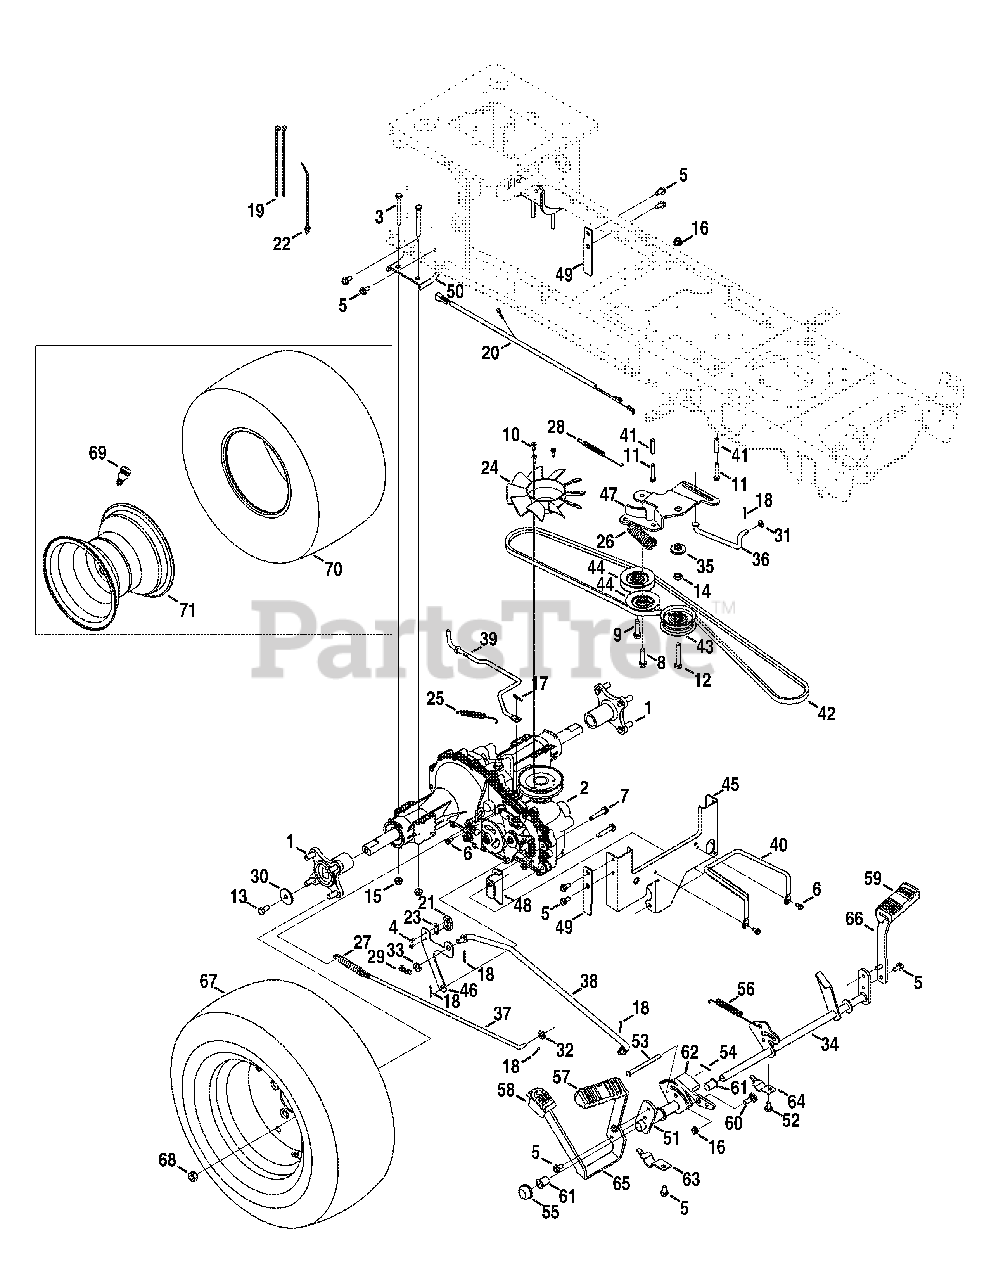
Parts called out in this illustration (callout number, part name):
1	Hub Assembly,Wheel
2	Transmission
3	Hex Screw, 5/16-18:3.00
4	Screw, #8-18:0.500
5	Taptite Screw, 5/16-18:.750
6	Taptite Screw, 1/4-20:0.500
7	Taptite Screw, 5/16-18:1.750
8	Taptite Sems Screw, 3/8-16:1.500
9	Taptite Sems Screw, 3/8-16:1.875
10	Screw, #12-24:0.625
11	Taptite Screw, 1/4-20:1.625
12	Hex Screw, 3/8-16:2.25
13	Hex Screw, 3/8-16:.750
14	Jam Nut, 7/16-20
15	Flangelock Nut, 5/16-18
16	Flangelock Nut, 3/8-16
17	Cotter Pin, .072 DIA. x 1.13 LG
18	Cotter Pin, 3/32:1.0
19	Cable Tie, 3/16 x .05 x 7.4
20	Jumper Harness
21	Short Spring Switch
22	Push Mount Cable Tie 7.5 LG
23	Insulator Nut Plate
24	Blade Fan
25	Extension Spring, .50 DIA x 5.0 LG
26	Extension Spring, 1.00 DIA x 4.75
27	Extension Spring, .59 OD x 4.00 LG
28	Extension Spring, .38 DIA x 5.6
29	Extension Spring, .375 OD x 1.44 LG
30	Flat Washer, .390 x 1.500 x .134
31	Flat Washer, .330 x .630 x .0635
32	Flat Washer, .344 x .750 x .120
33	Flat Washer, .407 x .812 x .135
34	Brake Control Assembly
35	Shoulder Spacer, 1.375 x .380 x .183
36	Footpedal Bypass Transmission Rod
37	Brake Rod
38	Control Rod
39	Disengage Rod
40	Belt Keeper, 5/16
41	Spacer, 260 x .372 x 1.420 LG
42	V Belt, 4L x 77.0
43	Flat Idler Pulley, 2.75 OD
44	V Idler Pulley, 3.06
45	Torque Bracket
46	Switch Bracket
47	Center Idler Bracket
48	Deck Bracket
49	Plate Bracket
50	Axle Bracket
51	Pedal Bracket Assembly
52	Taptite Screw, 5/16-18:0.625
53	Clevis Pin, 5/16 x 3.985
54	Bow-Tie Cotter Pin
55	Push Cap
56	Extension Spring, .63 DIA x 4.95 LG
57	Forward Pedal Pad
58	Reverse Pedal Pad
59	Brake Pedal Pad
60	Shoulder Bolt, .500 x .270:3/8-16
61	Flange Bearing, .630 ID x .695 OD x .60
62	Cruise Latch
63	Pedal Support Bracket
64	Pedal Support Bracket, 5/8
65	Drive Pedal Bracket
66	Brake Pedal Bracket
67	Complete Wheel
68	Lug Nut, 7/16-14
69	Air Valve
71	Rim Assembly
